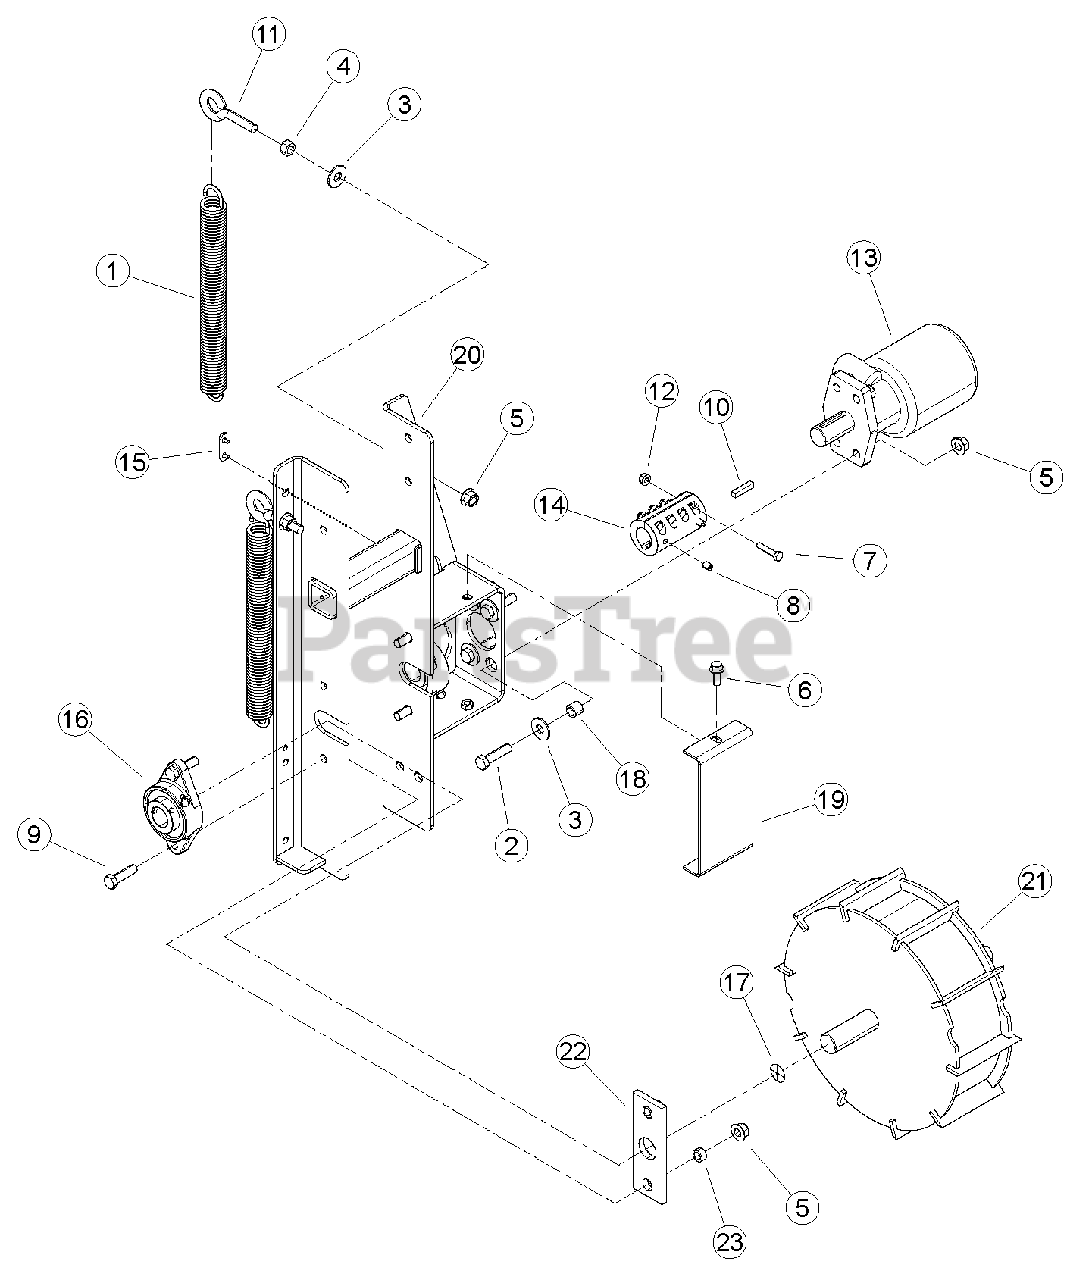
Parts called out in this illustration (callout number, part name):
1	SPRING, EXTENSION
2	BOLT, 1/2 X 2 GR5 HEX CAPSCREW ZP
3	WASHER, 1/2" FLAT ZP
4	NUT, 1/2" HEX NC ZP
5	NUT, 1/2-13 NYLOCK FLANGE
6	BOLT, 3/8 X 1 FLANGE NC
7	BOLT, 5/16 X 1-1/2 GR5 HEX CPS ZP
8	SET SCREW, 3/8 X 1/2 CUP PT SKT
9	BOLT, 1/2 X 1-3/4 GR5 HCPS NC ZP
10	KEY, 5/16 X 1-1/2 SQUARE
11	EYEBOLT, 1/2 X 2" ZP
12	NUT, 5/16-18 NYLOCK FLANGE
13	MOTOR, 45 CU IN HYDRAULIC
14	BEARING, 1-1/4" DIA 2 BOLT FLANGE
15	COUPLER, 1-1/4 SHAFT
16	WEAR PAD, STD. SPRING HD FRONT
17	DECAL, ROTATING SHAFT
18	SPACER, 0.75 X 0.620
19	SHIELD, COUPLER
20	WELDMENT, ROLLER SLIDE
21	WELDMENT, TOP GRAB ROLLER
22	BEARING, SLIDE
23	SPACER, .75 OD X .5 ID X .37
